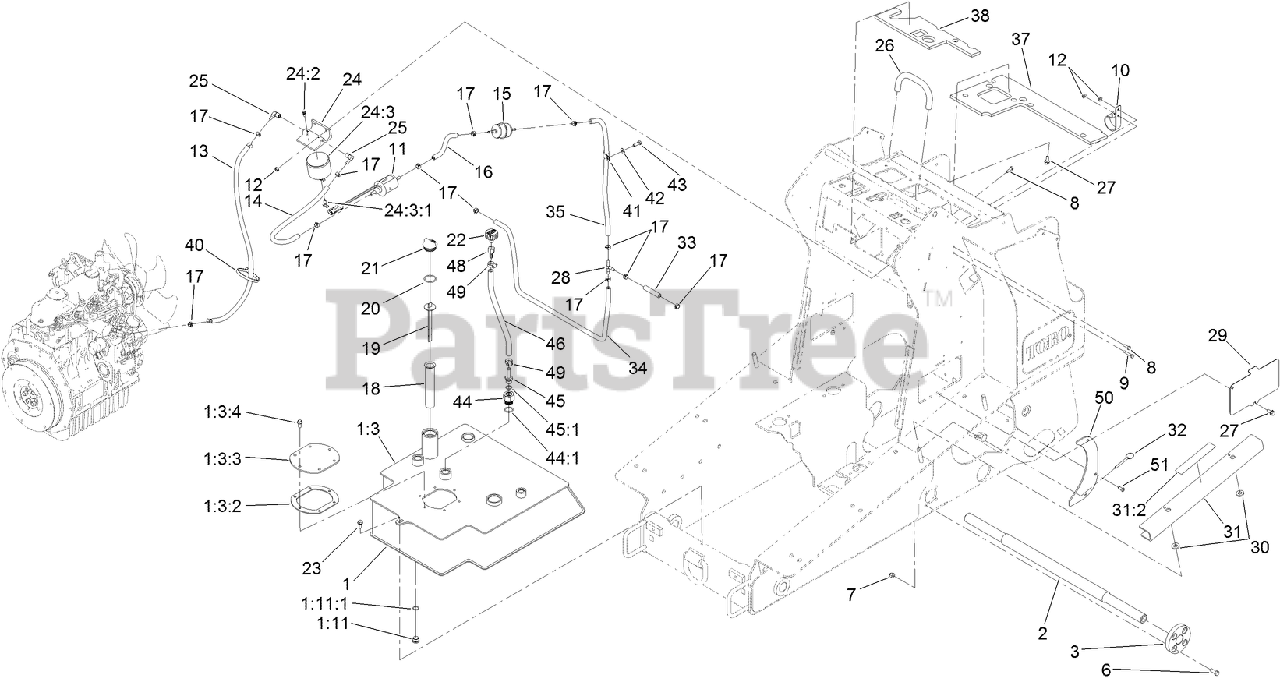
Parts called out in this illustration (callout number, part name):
1	TANK-HYD
1:3	TANK TOP ASM
1:3:2	GASKET-COVER, ACCESS
1:3:3	COVER-TANK
1:3:4	SCREW-HHF
1:11	PLUG-HEX
1:11:1	O-RING
2	SHAFT-TRACK
3	HUB-SHAFT
6	SCREW-HH
7	NUT-LOCK, NI
8	SCREW-HH
9	SCREW-HH
10	BRACKET-PUMP, FUEL
11	PUMP-FUEL
12	NUT-HF
13	HOSE-FUEL
14	HOSE-FUEL
15	FILTER-INLINE
16	HOSE-FUEL
17	CLAMP-HOSE
18	FILTER-SCREEN
19	DIPSTICK
20	O-RING
21	PLUG-PLASTIC
22	BREATHER
23	SCREW-THD ROLL, HWH
24	FILTER HEAD ASM
24:2	VENT-AIR
24:3	ELEMENT-SPIN ON
24:3:1	VALVE-DRAIN
25	FITTING-HYD, 90
26	BAR-REFERENCE
27	SCREW-HHF
28	FITTING-TEE, BARBED
29	PLATE-COVER, ACCESS
30	WASHER-NEOPRENE
31	ARM-LOCKING
31:2	DECAL-DANGER
32	PIN-COTTERLESS
33	HOSE-FUEL
34	HOSE-FUEL
35	HOSE-FUEL
37	FOAM-HEAT SHIELD
38	FOAM-HEAT SHIELD
40	TIE-CABLE
41	CLAMP-R
42	WASHER-FLAT
43	SCREW-HH
44	FITTING-STRAIGHT
44:1	O-RING
45	FITTING-STR
45:1	O-RING
48	FITTING-FEMALE, BARBED
49	CLAMP-HOSE
50	PLATE-DIRT
51	SCREW-BHTF
